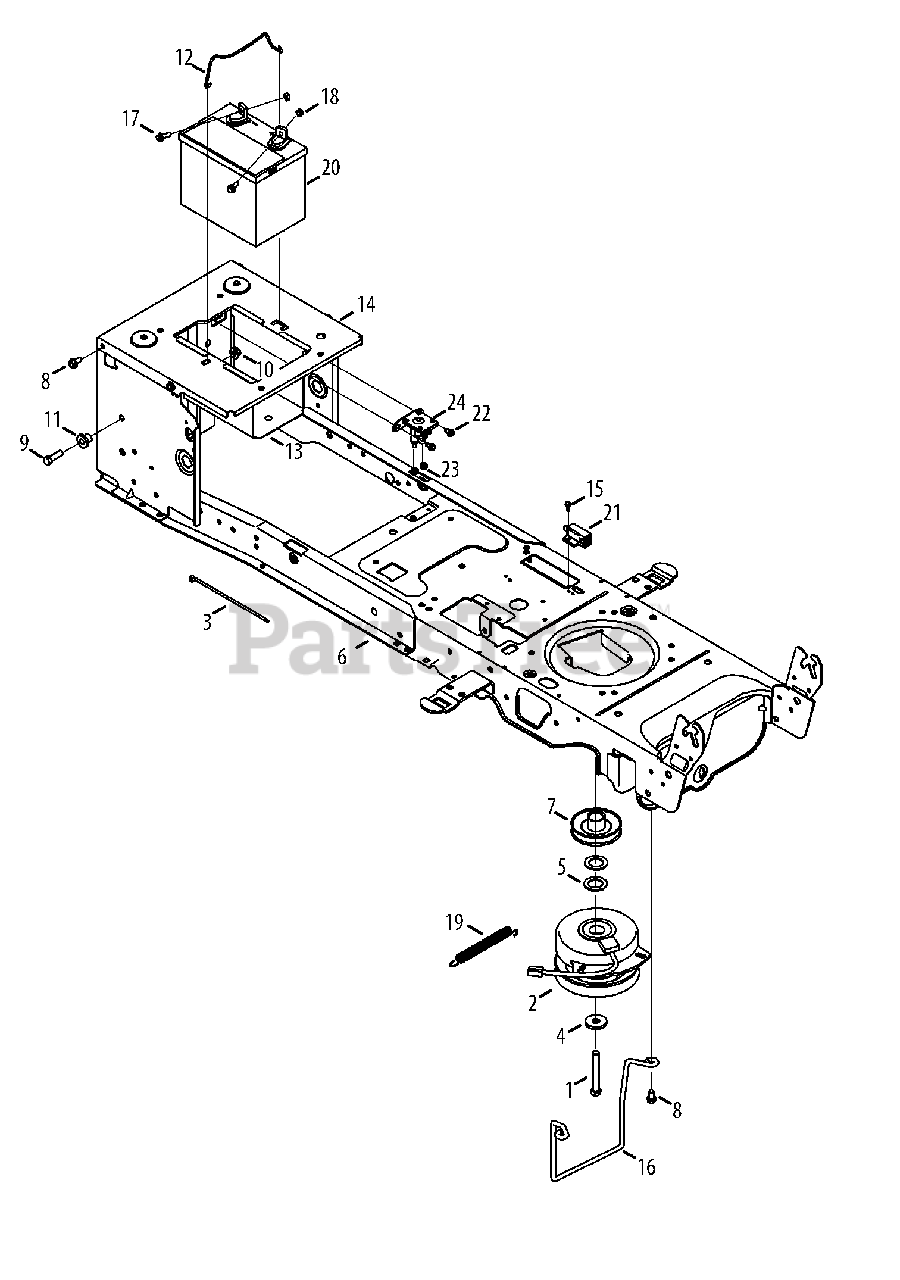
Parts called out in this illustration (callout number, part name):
1	Hex Head Screw, 7/16-20:3.50
2	Electric PTO Clutch
2	Clutch Harness Wire 11.625"
3	Cable Tie, 3/16 x .05 x 7.4
4	Washer, Flat, .450 x 1.25 x .164
5	Flat Washer, 1.031 x 1.620 x .095
6	Frame
7	Electric PTO Engine Pulley
8	Taptite Screw, 5/16-18:.750
9	Hex Head Screw, 3/8-16:1.25
10	Flangelock Nut, 3/8-16
11	Shoulder Spacer, .38 x 1.0 x .70
12	Battery Holder Rod
14	Seat Frame Bracket
15	Shoulder Screw, #10-32:.500
16	Belt Keeper Rod
17	Hex Head Flange, 1/4-20:.75
18	Sems Nut, 1/4-20
19	Spr, Extn, .56 Dia X 5.52
21	Interlock Switch
22	Taptite Screw, 1/4-20:0.375
23	Flangelock Nut, 1/4-20
24	Solenoid, 12 V
